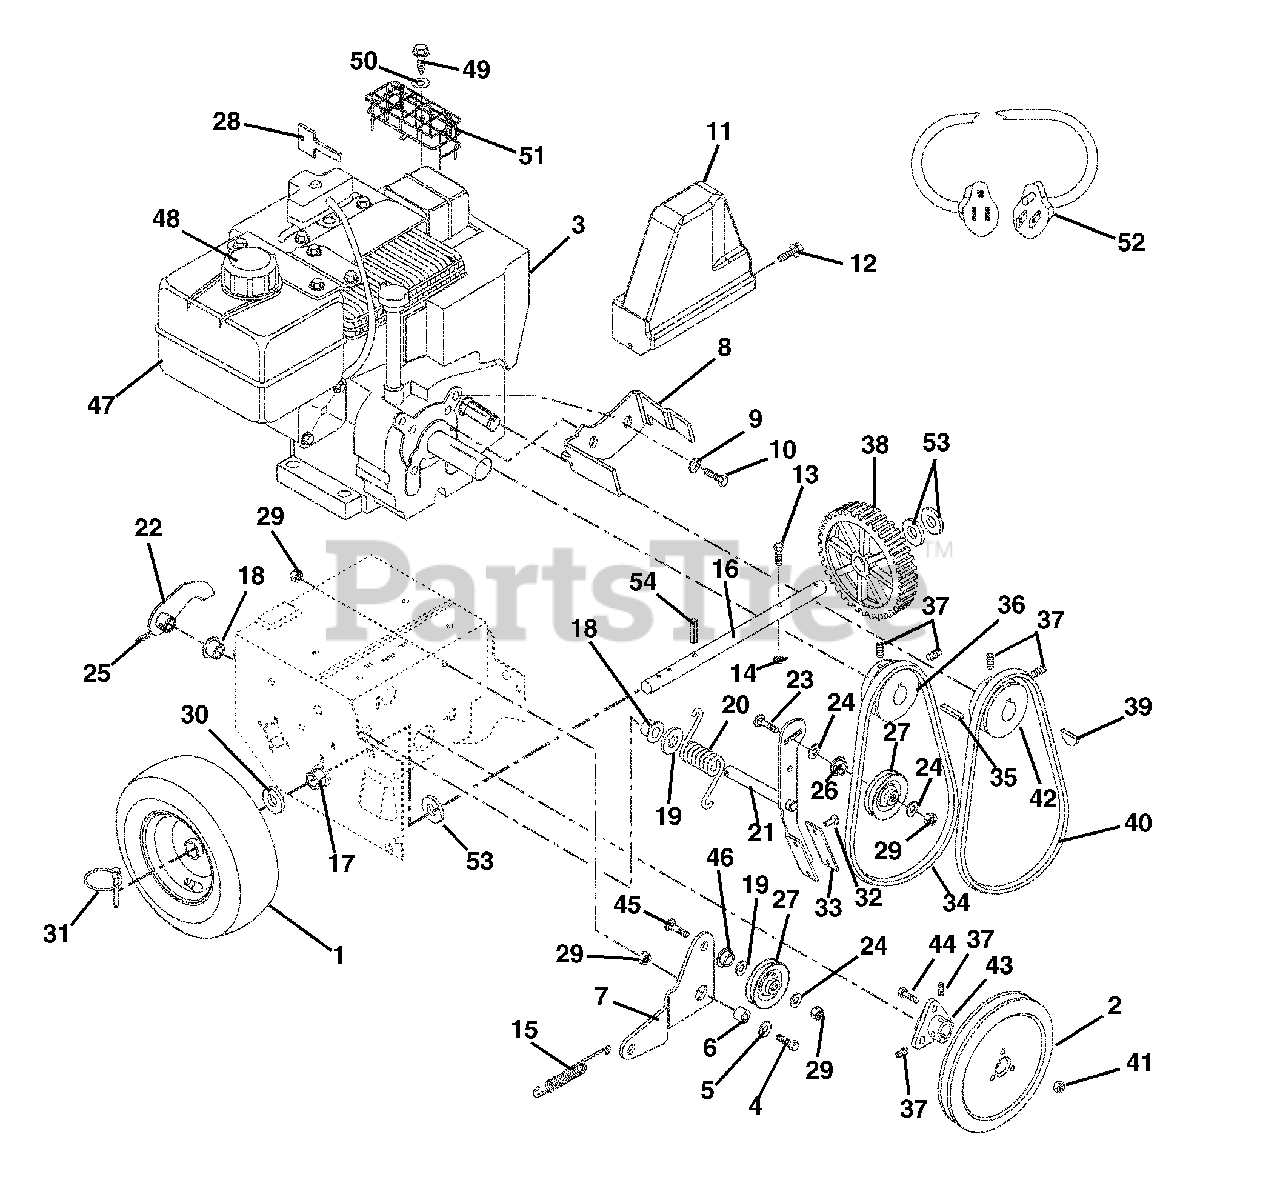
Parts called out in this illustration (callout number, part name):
1	WHEEL 5.00 X 6.00
1	TIRE
1	TIRE/WHEEL ASSY 4.10-6 PIN-LOK
2	PLY-V 8.0 X 1.25 3BLT SALEM
3	ENGINE, TECUMSEH HSSK50 120V
3	ENGINE, 7HP OHV TEC. - 120V
3	ENGINE, TECUMSEH HSSK50
3	ENGINE, 7HP OHV TEC. - RECOIL
4	@BLT-HEX .31-18X.75 GR5 YWZC
5	@WSHR-FL-STL.38X.875X.083 YWZC
6	SPACER BUSHING .5 X .32 X .163
7	IDLER ARM
8	FINGER, BELT
9	@WSHR-LK .31X.078 REG YWZC
10	BLT-HEX .31-24X.75 YWZC GR5
11	COVER, BELT
12	@SCR-TAP .25-20X.37 HWH YWZ TR
13	BLT-HEX .25-20X1.75 GR8 YWZC
14	@NUT-LK-CTR .25-20 YWZC
15	SG-TENS .047X.44X3.37 WLD 1.47
16	AXLE SHAFT
16	SHAFT, AXLE - COMPACT PIN-LOCK
17	BSHG-FLG .750X.873HEXX.53X1.18
18	BSHG-FLG.500X.625X.312X.750NY
19	WSHR-FL-STL .520X.810X.033YWZC
20	SG-TORS .148X1.0X1.53
21	CLUTCH ARM W/BRAKE PAD
22	ARM-CLUTCH
23	@BLT-RDHDSQNK .31-18X1.25 G5YZ
24	@WSHR-FL-STL.38X.875X.083 YWZC
25	PIN-ROLL .156X.88
26	SPCR, BRG .315X.50X.688X.281
27	IDLER
28	KEY, PUSH/PULL - TECUMSEH
29	@NUT-LK-CTR .31-18 YWZC
30	WSHR-FL-STL.754X1.125X.062YWZC
31	PIN-LOK .31X1.75
32	RVT-TBLR .187X.437 RH ST PL
33	BRAKE LINING
34	BELT,4L TO BE REPLACED07200021
34	V-BELT, 4L-RAW EDGE
35	KEY-SQ .188X1.0X.188 SAE 8630
36	SHEAVE-ENGINE
36	SHEAVE - ENGINE
37	SCR-SET .31-18X.38 SKHCUPDL
39	KEY-WDRF .125X.625X.250 SAE5
40	V-BELT, 3L-COGGED
41	@NUT-SPNLK-FLG .312-18 YWZC
42	SHEAVE - CAMSHAFT
44	BLT-SERRDHD SL .31-18X.75 YZ
45	@BLT-RDHDSQNK .31-18X1.25 G5YZ
46	BSHG, FLG .325X.499X.26X.88
47	PLUG, SPARK
48	CAP, FUEL - TECUMSEH
49	SCR-TAP 10-16X.75 YWZC
50	@WSHR-FL-STL.219X.50X.049 YWZC
51	MUFFLER GUARD 5 HP
52	CORD, ELECTRIC START CORD 120V
53	WSHR-FL-STL .755X1.25X.125 YZ
54	PIN-ROLL .188X1.25
